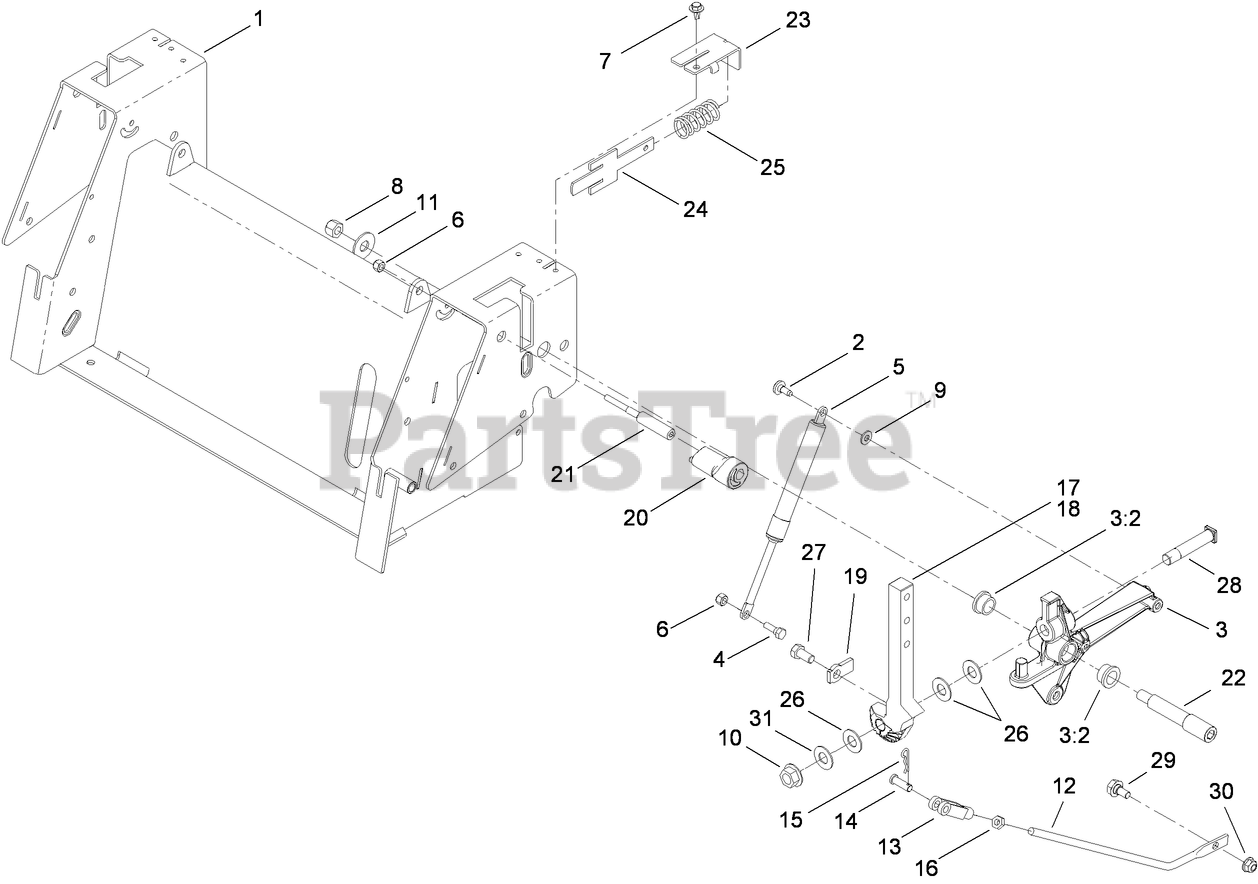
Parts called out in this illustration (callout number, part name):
1	BOX-CONTROL
3	ACTIVATOR ARM ASM
3:2	BUSHING
4	BOLT-SHOULDER
6	NUT-LOCK, NI
7	SCREW-HHFTF
8	NUT-LOCK, NI
9	WASHER-FLAT
10	NUT-HF
11	WASHER-FLAT
12	LINK-BENT, HYDRO
13	YOKE-ADJUSTABLE
14	PIN-CLEVIS
15	PIN-COTTER
16	NUT-JAM
19	TAB-STOP
20	ECCENTRIC
21	SCREW-ECCENTRIC
22	BOLT-SHOULDER
23	BRACKET-RETURN
24	PLATE-RETURN
25	SPRING-COMPRESSION
26	WASHER-PIVOT
27	SCREW-HH
28	BOLT-SHOULDER
29	BOLT-SHOULDER,HFH
30	NUT-HF, NI
31	WASHER-TEFLON
